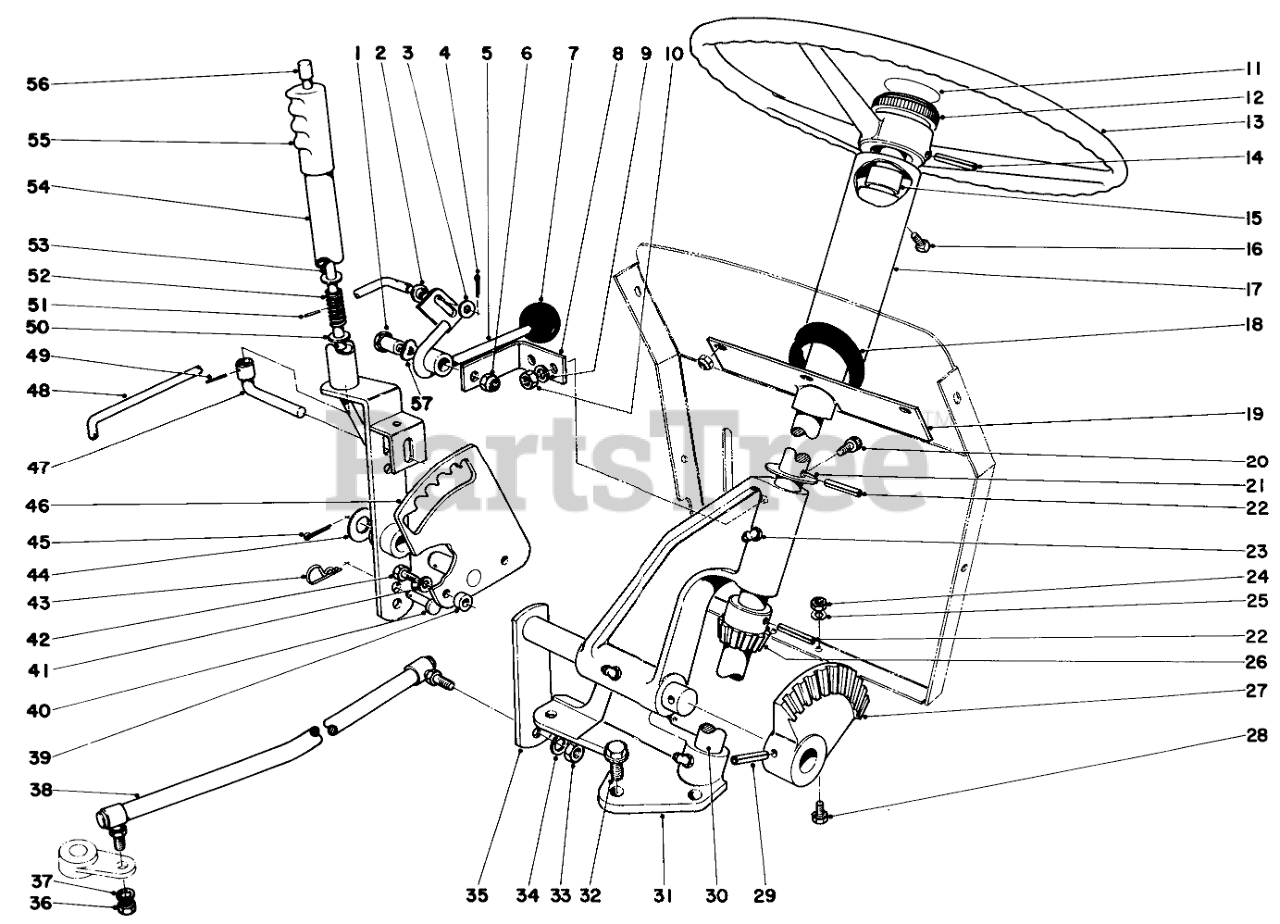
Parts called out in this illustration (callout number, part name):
2	Bushing
3	WASHER-FLAT
4	PIN-COTTER
5	Clutch Lever
6	Nut
7	Knob
8	Idler Bracket
9	WASHER-LOCK
10	NUT-HEX
11	Decal Steering Cap
12	Steering Cap
13	Steering Wheel
14	Roll Pin
15	BUSHING
16	SCREW-SQH
17	Cover Steering Support
18	Grommet
19	Steering Tube Incl. Ref. No. 15
20	Screw
21	WASHER-FLAT
22	PIN-ROLL, SLOTTED
23	Grease Fitting
24	NUT-HEX
25	WASHER-LOCK
26	Pinion Gear
27	Steering Gear
28	Sems Screw
29	Roll Pin
30	Steering Shaft
31	Steering Gear Support
32	Screw-HH
33	NUT-HEX
34	WASHER-LOCK
35	Steering W.A.
36	NUT-HJ
37	WASHER-LOCK
38	Steering Rod
39	Spacer
40	Pin
41	WASHER-LOCK
42	SCREW-HH
43	PIN-COTTER, HAIR
44	PIN-COTTER
45	Washer
46	Quadrant
47	Lift Lock
48	Clutch Rod
49	PIN-SPRING
50	Washer
51	Roll Pin
52	Spring
53	Lift Rod
54	Lower Handle
55	Handle Grip
57	Wavy Washer
